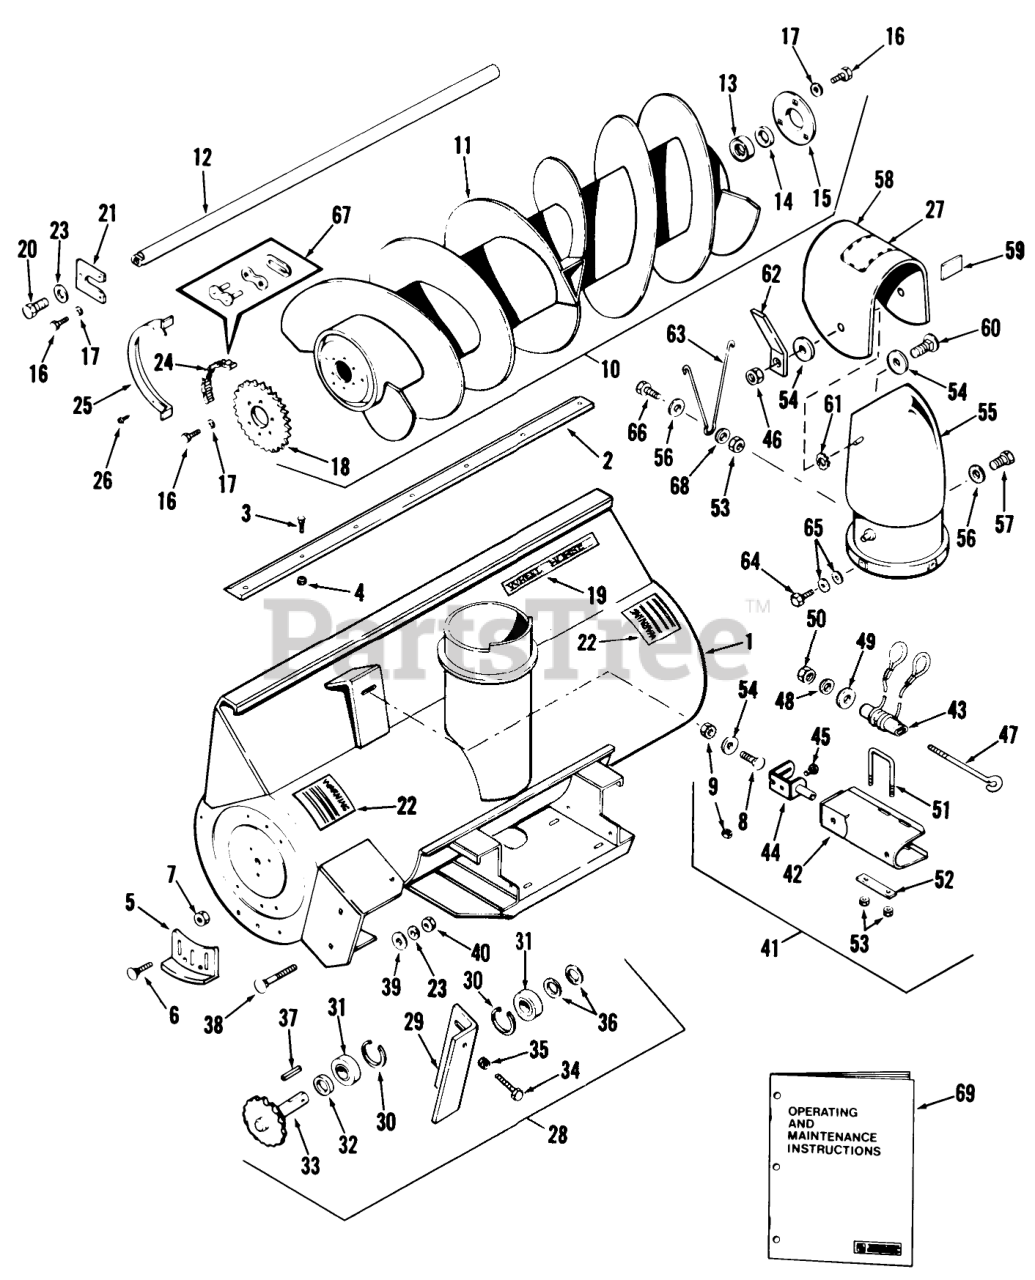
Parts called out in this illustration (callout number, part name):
1	Assembly-Header Housing
1	Assy.-Header Hsg. 48"
2	Blade-Scraper
3	Bolt 1/4-20 X 5/8
4	Nut 1/4-20
5	Shoe-Skid
6	Bolt
7	Keps Nut 5/16-18
8	Bolt
10	Auger Assembly
11	Auger
12	Auger Shaft
13	Bearing
14	Washer
15	Spring
16	Bolt
17	Lockwasher
18	Control Rod-Traction
19	DECAL-WHEEL HORSE
20	Bolt
21	PLATE AUGER MOUNTING
22	Decal
23	Lockwasher
24	Auger Drive Chain #40
24	CHAIN-AUGER DRIVE
25	Chain Guard
26	SCREW
27	Decal-Caution
28	Jackshaft Assembly
28	Spacer
28	Jackshaft Housing w/Bearings
29	Jackshaft Housing
30	Ring-Snap
31	BEARING-GEAR BOX
32	Spacer
33	Jackshaft and Sprocket
34	S.T. Bolt 5/16-18 x 2
35	Jam Nut 5/16-18
36	WSHR SPROCKET TO BRG
38	Carriage Bolt 1/2-13 x 3 1/2
39	Washer 1/2 SAE
40	Eslok Nut
41	Stack Drive Bracket
42	SHROUD-STACK DRIVE
43	ASSEMBLY CABLE
43	Tube
43	Cable
43	Oval Sleeve
44	Bracket and Tube
45	Bolt-Carriage
46	Nut
47	EYE BOLT DRIVE TUBE
48	Spring Washer
49	Washer
50	NUT
51	U-BOLT
52	Friction Strap
53	Nut
54	WASHER
55	Elbow and Pivot Assembly
56	Washer
57	Bolt
58	Deflector Elbow
59	MOLDING DEFLECTOR
60	Bolt-Carriage
61	Washer 5/16 (Special Locking)
62	STRAP-LOCKING
63	Spring Hook
64	H H C S
65	Washer
66	Bolt
67	Chain Repair Kit
68	Spacer
69	Operating and Maintenance Instructions
